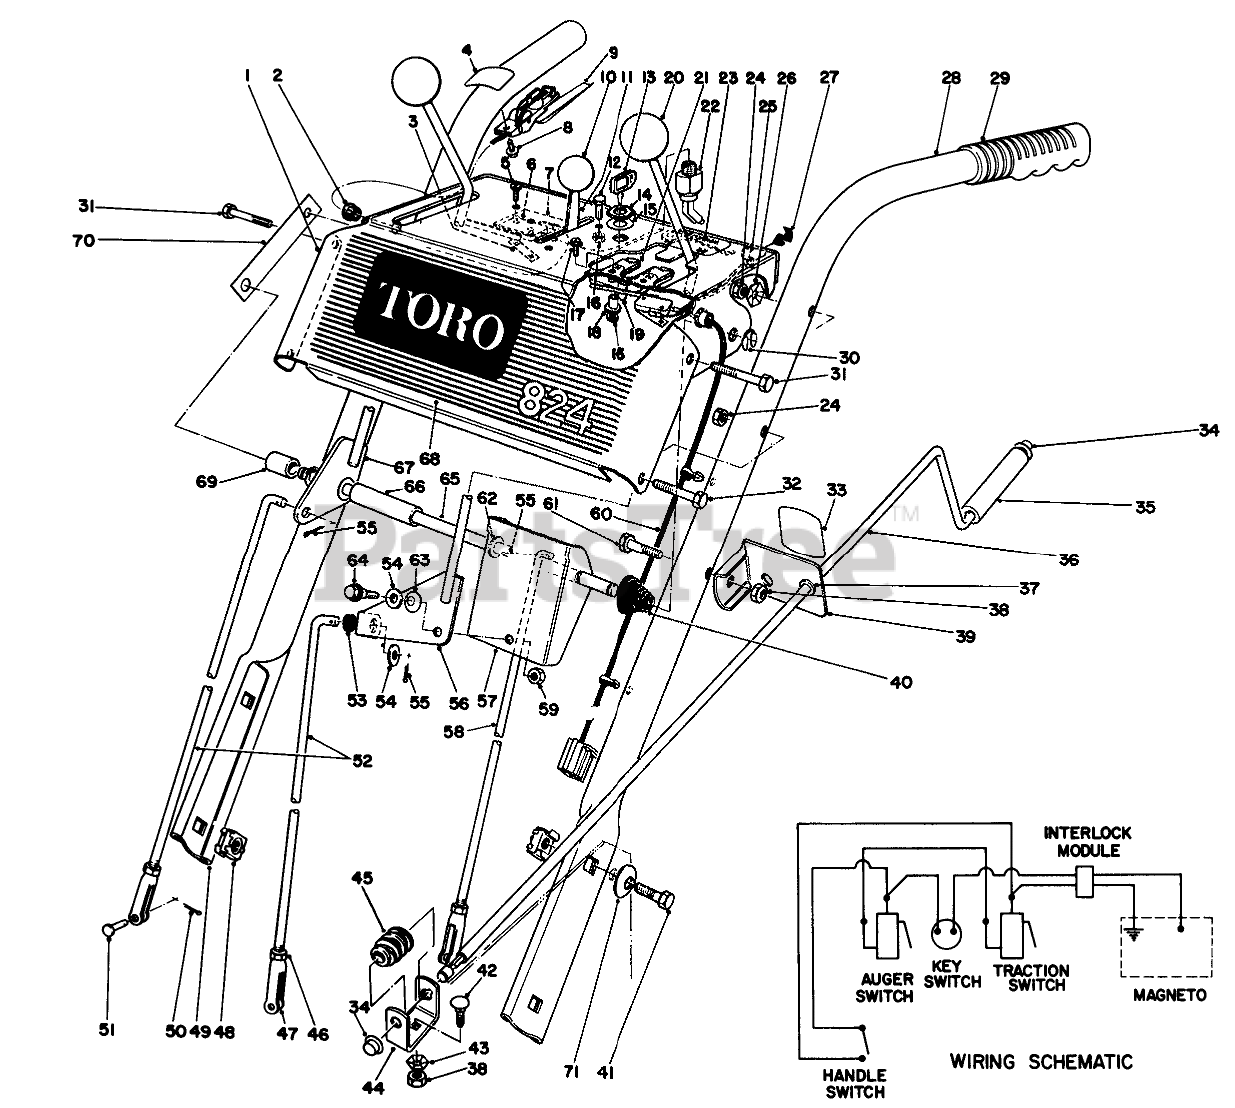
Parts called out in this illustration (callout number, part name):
1	ESCUTCHEON PLT B
2	BUSHING NYLON
3	NUT-SPEED
4	INTERLOCK DECAL
5	Screw-Pan Hd. Machine
6	SWITCH-MICRO
7	SWITCH MTG PAD
8	SCREW
9	INTERLOCK HDLE SWITCH
10	CONTROL KNOB
11	THROTTLE CONTROL
12	HEX HEAD SEMS 10-24X1/2
13	KEY-IGNITION
14	NUT-HH
15	WASHER-TOOTH, INTERNAL
16	NUT-LOCK, NI
17	10-24 X 7/8 RND HD MS
18	INTERLOCK SPACER
19	INTERLOCK SPRING
21	INTERLOCK SLIDE
22	Switch-On/Off (Incl. Ref. #14 & 15)
23	INSTR DECAL
24	NUT-LOCK, NI
25	BEARING NYLINER
26	Washer
27	Stud-Mounting
28	LEFT HANDLE
29	Grip Handle
30	RING-CLIP
31	SCREW-HH
32	SCREW-HH
33	DECAL-CHUTE DIRECTION
34	RETAINER-PUSH ON
35	Grip-Rod
36	Rod-Chute Control
37	Bushing
38	NUT-LOCK, NI
39	Bracket-Chute Control (Incl. Ref. #33 & 37)
40	CONICAL SPRING
41	SCREW-HH
42	BOLT-CARR
43	WASHER-LOCK
44	BRACKET-WORM
45	GEAR-WORM, CHUTE
46	NUT-HJ
47	CLEVIS
48	Retained Nut
49	HANDLE RIGHT
50	PIN-COTTER
51	PLUG-PIPE, SQH
52	SPEED SELECTOR ROD
53	GROMMET-RUBBER
54	WASHER-FLAT
55	PIN-COTTER
56	SHIFT LEVER WA
57	SHIFT BRACKET
58	TRACTION CONTROL ROD
59	NUT-LOCK, CONE
60	WIRE HARNESS INTERLOC
61	SCREW-HH
62	WASHER-FLAT
63	7/16 SPRING WASHER
64	SHOULDER SCREW
65	PIVOT ROD
66	SHIFT LEVER SPACER
67	LEVER WA
68	DECAL - ESCUTCHEON 824
69	AUGER LEVER SPACER
70	ESCUTCHEON SUPT STRAP
71	WASHER-SPRING
